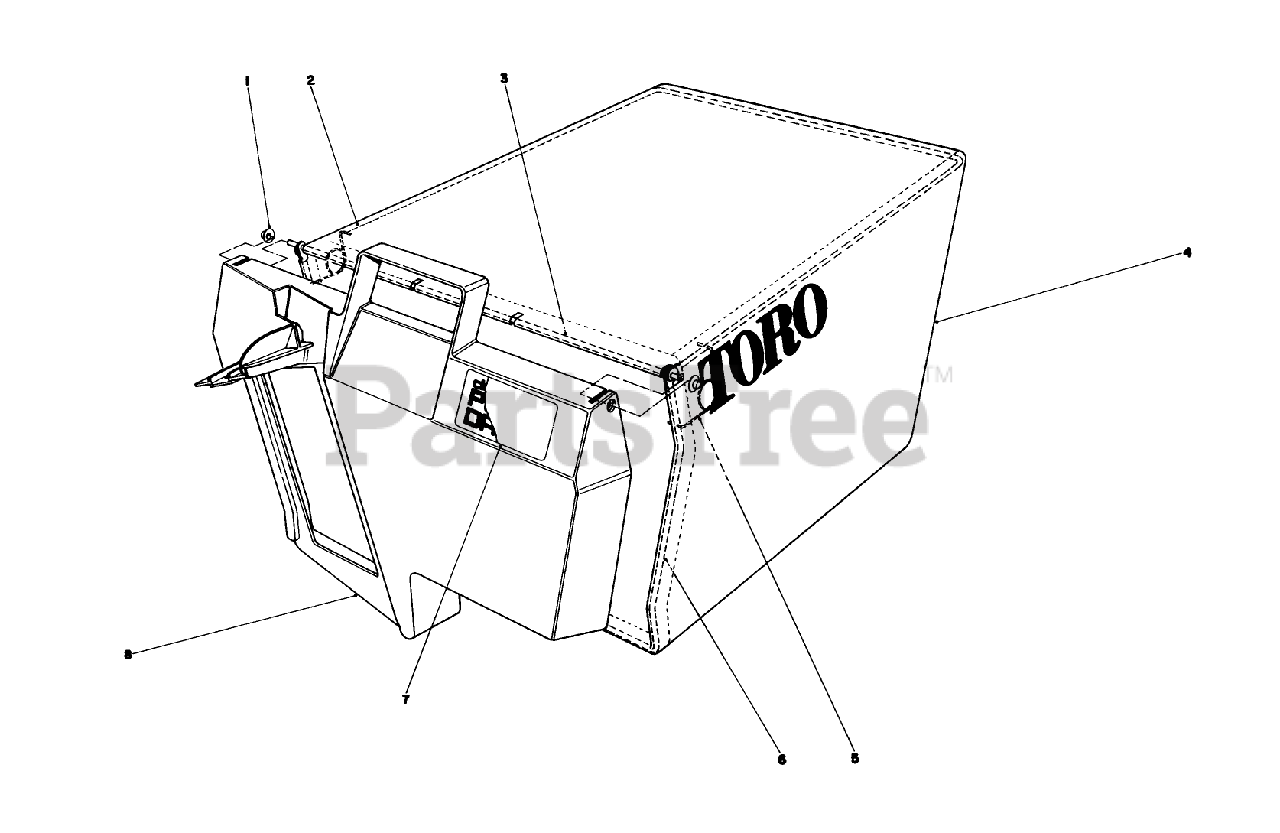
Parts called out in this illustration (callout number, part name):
1	NUT-PUSH
2	Bag Frame Upper
3	HINGE-DOOR, BAG
4	Bag
5	SPRING
6	Frame Bag
7	BAG DOOR DECAL
8	Door Grass Bag
